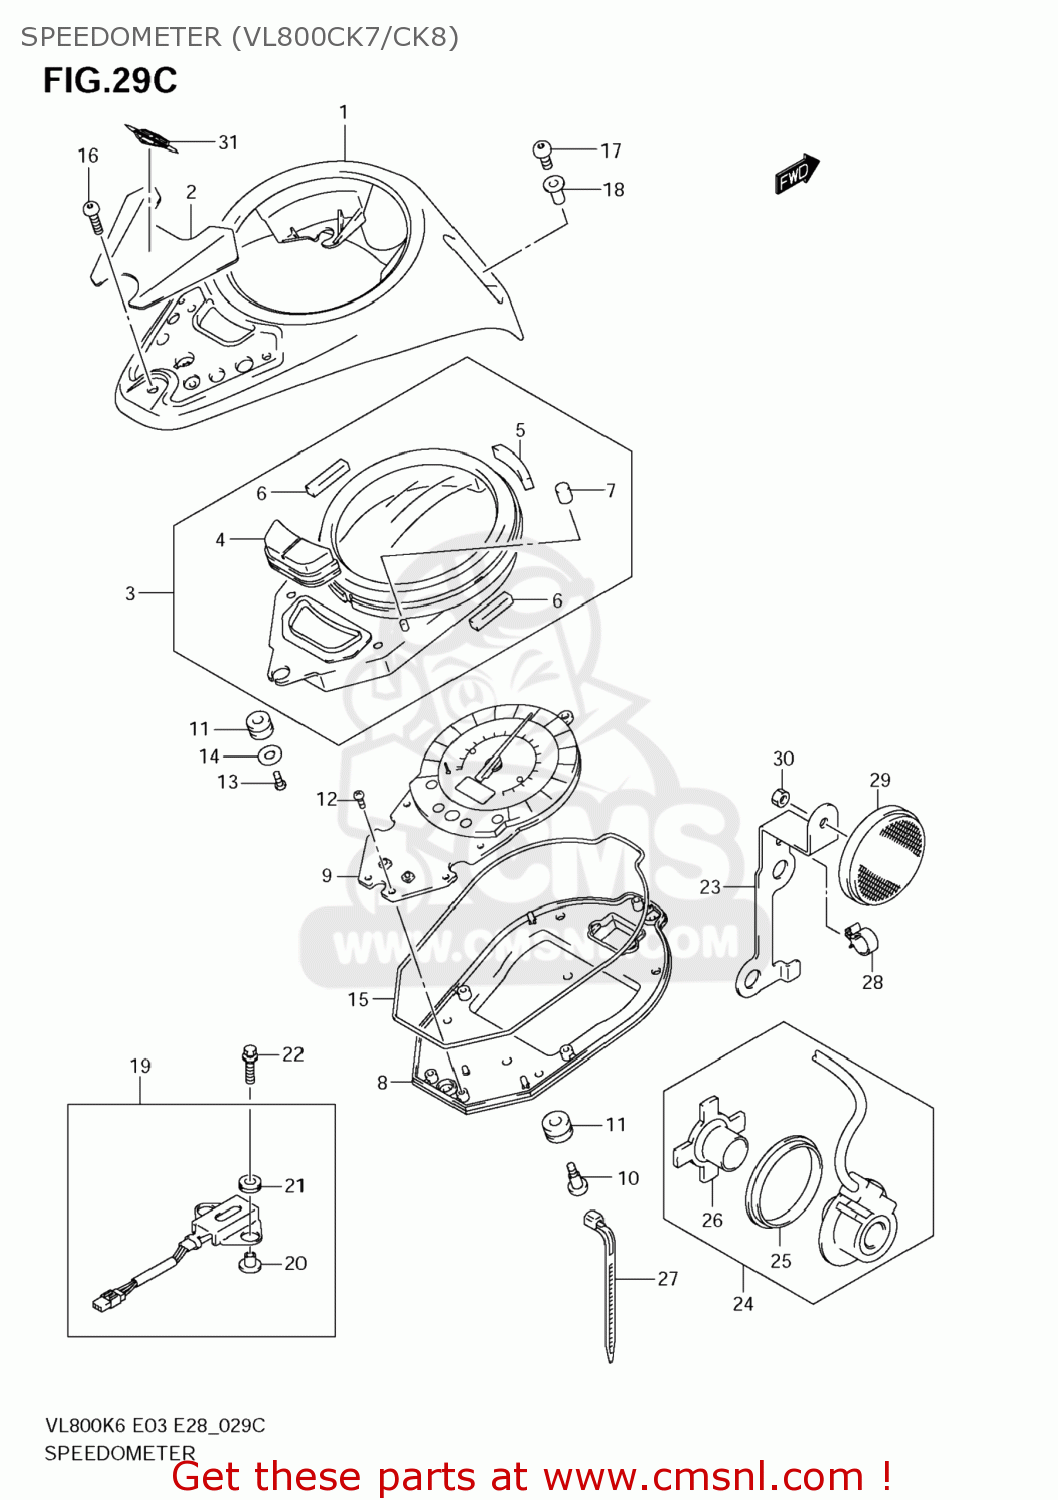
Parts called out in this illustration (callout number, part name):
1	CASE ASSY
2	PLATE,DECORATION
3	CASE,UPR
4	SWITCH,SELECT
5	CUSHION NO.1
6	CUSHION NO.2
7	CUSHION NO.4
8	CASE,LWR
9	SPEEDOMETER
10	BOLT
11	CUSHION,METER
12	SCREW(3X10)
13	SCREW(4X14)
14	WASHER
15	GASKET,METER CASE (NAS)
16	SCREW(5X14)
17	SCREW(5X18)
18	NUT
19	RESISTOR ASSY
20	SPACER(6.5X10X11.6)
21	CUSHION
22	BOLT(6X25)
23	GUIDE,SPEED SENSOR LEAD
24	SENSOR,SPEED
25	SEAL,OIL(44X55X6)
26	MAGNETO
27	CLAMP(L:145)
28	CLAMP
29	REFLECTOR,REFLEX FR
30	NUT
31	EMBLEM,BOULEVARD
